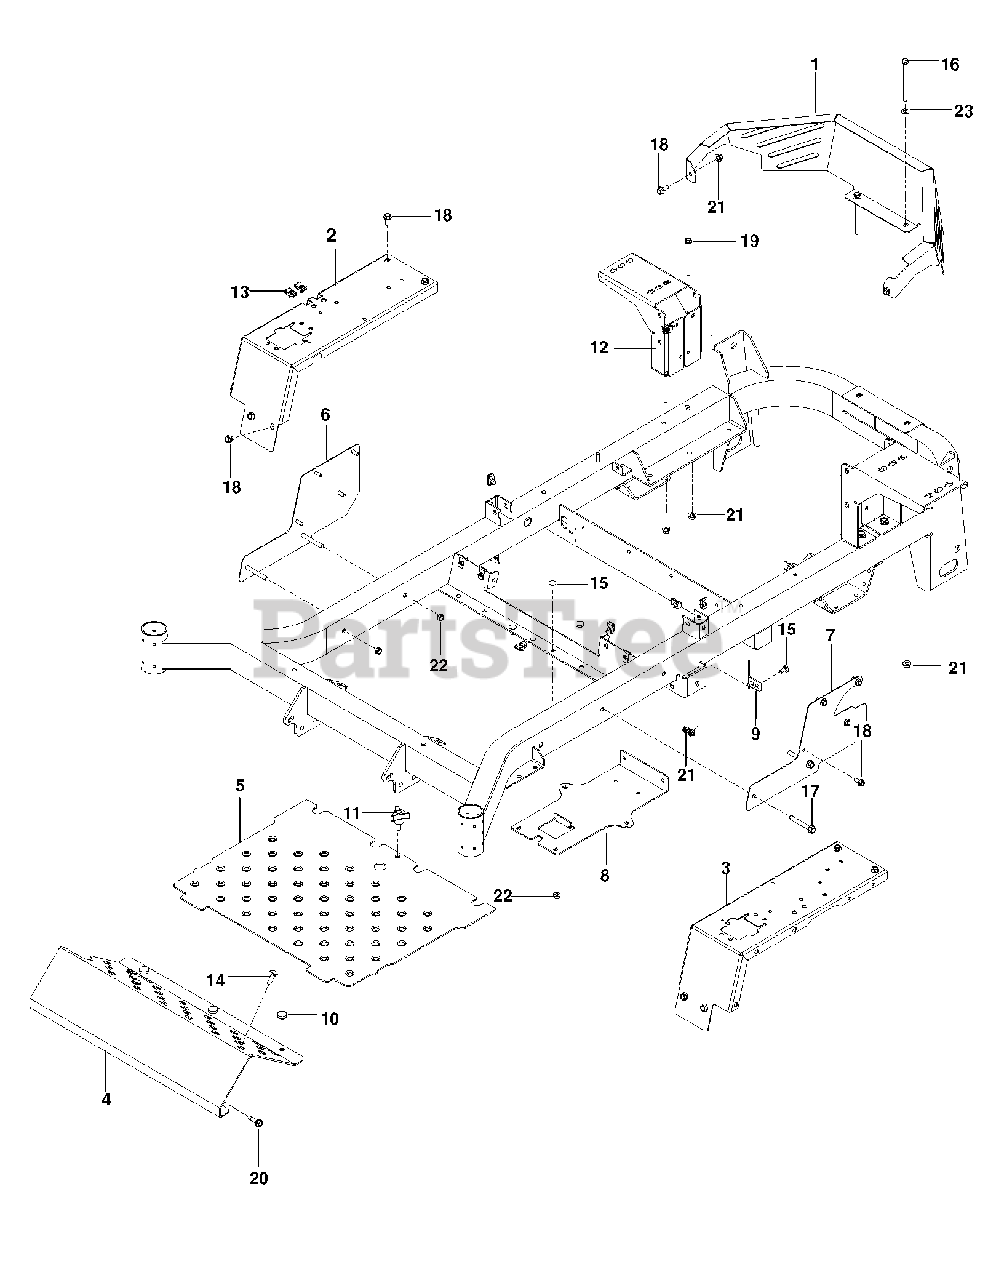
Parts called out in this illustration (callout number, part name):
1	GUARD, REAR ULTRA, BLUE
4	PLATE, FOOT REST - RAM DK BLUE
5	FLOOR PAN W/DECALS
6	SIDE, RT, BL
7	SIDE, LT, BL
8	PLATE, BATTERY, BLACK
10	GROMMET, BUMPER
11	KNOB W/STUD
12	MOUNT, TANK, ZT BLK
13	U-CLIP 5/16-18 NUT RETAINER
14	RHSNB 5/16C X 1
15	BOLT 5/16C X 3/4" CARRIAGE
16	HCS 5/16C X 4
17	HHFS 3/8-16 X 2 3/4
18	HHFS 5/16-18 X 3/4
19	HHFS 5/16-18 X 3 3/4
21	5/16-18 NYLOC FLANGE NUT
22	NUT HEX 3/8-16 NYLON, THIN
23	FLAT WASHER 5/16 SAE
